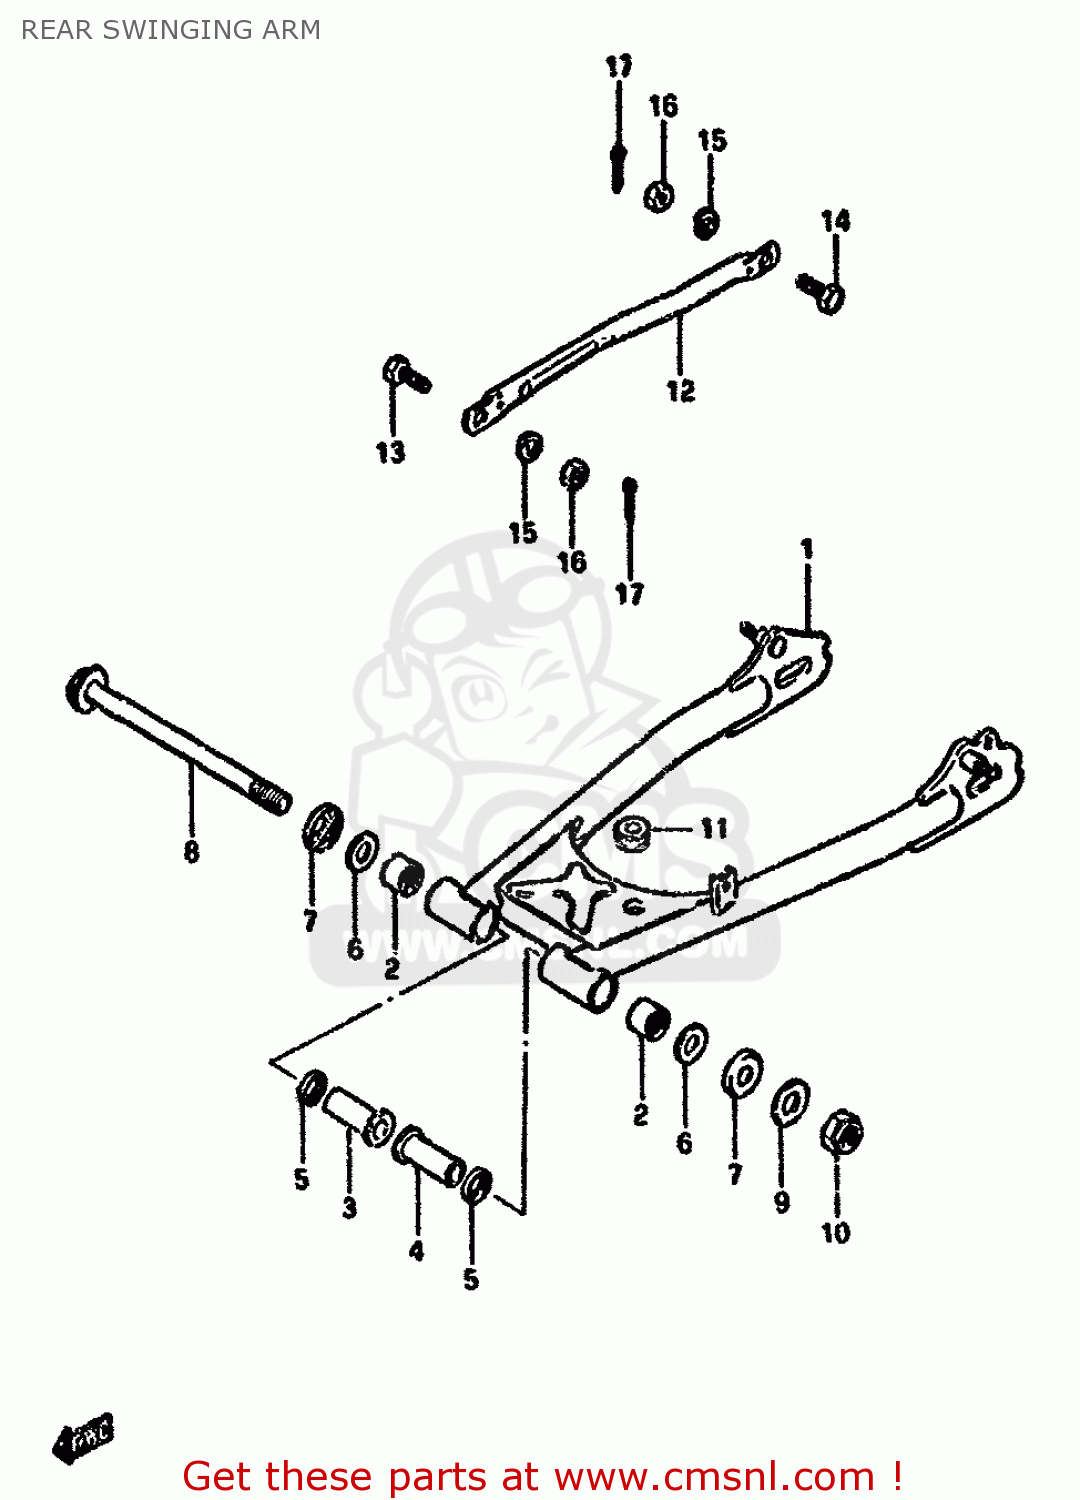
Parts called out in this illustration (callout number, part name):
1	SWINGINGARM ASSY,RR
2	BEARING(20X27X20)
3	SPACER,RR SWGARM PIVOT,R
4	SPACER,RR SWGARM PIVOT,L
5	SEAL,OIL(20X27X5)
6	WASHER
7	COVER,RR SWINGINGARM PIVOT
8	SHAFT,REAR SWING ARM
9	WASHER
10	NUT 14MM
11	CUSHION
12	TORQUE LINK,REAR BRAKE (
13	BOLT(8X22.5)
14	BOLT(8X26.5)
15	WASHER,LOCK
16	NUT
17	PIN 20X20
